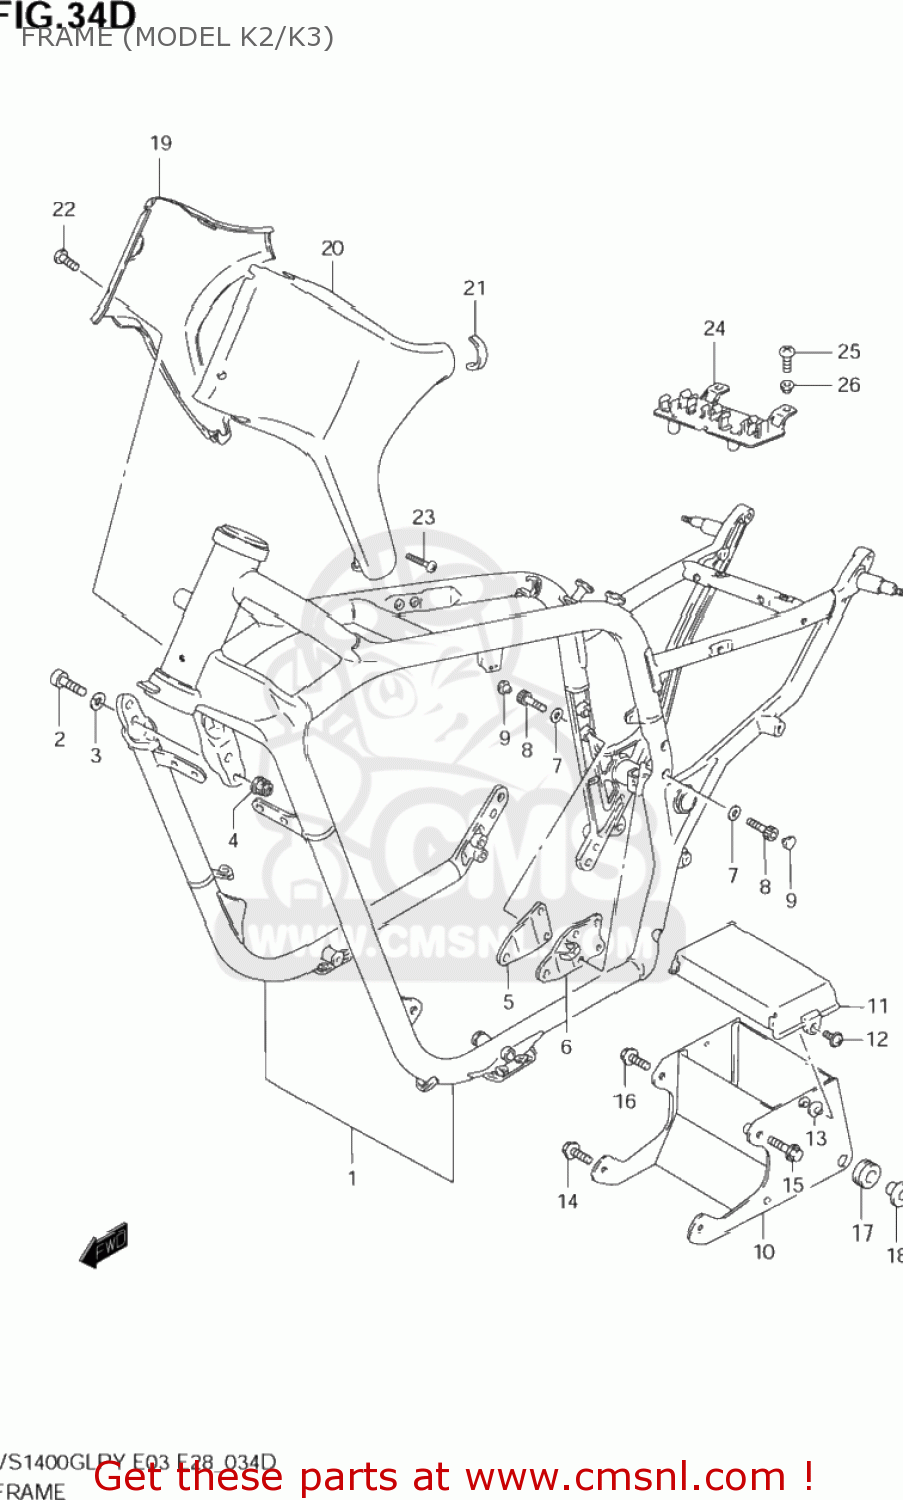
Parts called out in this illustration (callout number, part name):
1	FRAME SET
2	BOLT(10X33)
3	WASHER
4	NUT
5	PLATE,MOUNT NO.4,R
6	PLATE,MOUNT NO.4,L
7	WASHER
8	BOLT(8X32)
9	CAP(OD:14.5)
10	HOLDER,BATTERY
11	COVER,BATTERY
12	SCREW(5X12)
13	WASHER
14	BOLT
15	BOLT, FRONT
16	BOLT(8X40)
17	CUSHION
18	BUSH
19	COVER,FRAME HEAD,R(BLACK)
20	COVER,FRM.HD.,
21	PROTECTOR,FRAME HEAD COVER
22	SCREW 6X10
23	SCREW
24	HOLDER,COUPLER
25	SCREW
26	WASHER
